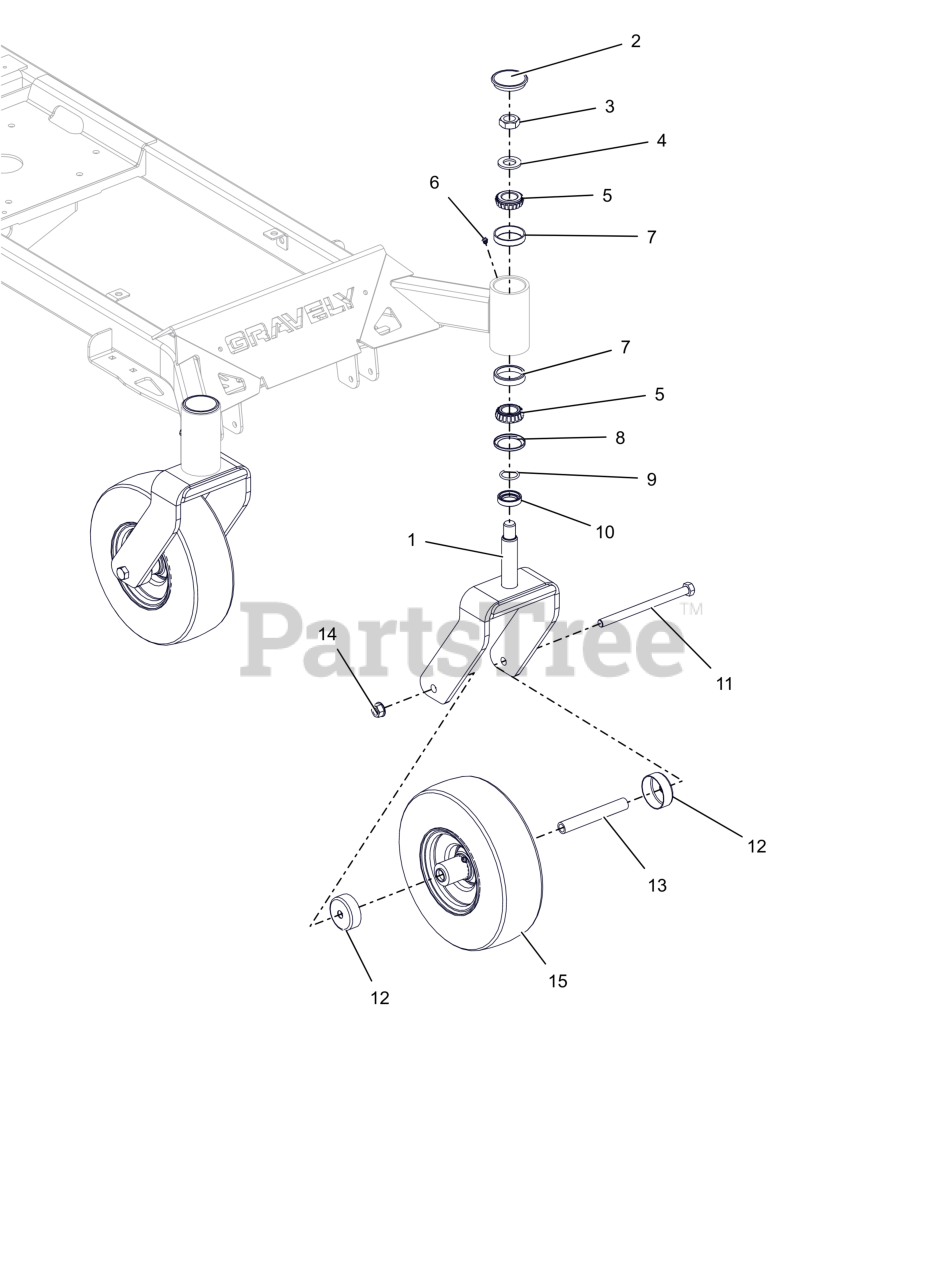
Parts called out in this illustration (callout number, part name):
1	WLDMT, CASTER FORK
2	CAP, DUST
3	NUT, JAM-TOPLOCK .750-16 ZCC
4	WSHR-FL-STL 0.812X1.469X0.134 ZCC
5	BRG-CONE 1.0X.58
6	FTG, .25-28 FLUSH MNT GREASE
7	BRG-CUP1.980X.420
8	BEARING SEAL 1.5 X 2 X .18
9	O-RING 1.000X1.250X
10	SPCR, CASTER FORK (1.00)
11	BLT, HEX 0.5-13X7 GR5 ZCC
12	SHIELD, WHEEL BEARING
13	SPACER, ROLLED WHEEL
14	NUT-LK-CTR-FLG .500-13 GG ZCC
15	ASM, WHL/TIRE 11X4.00-5
